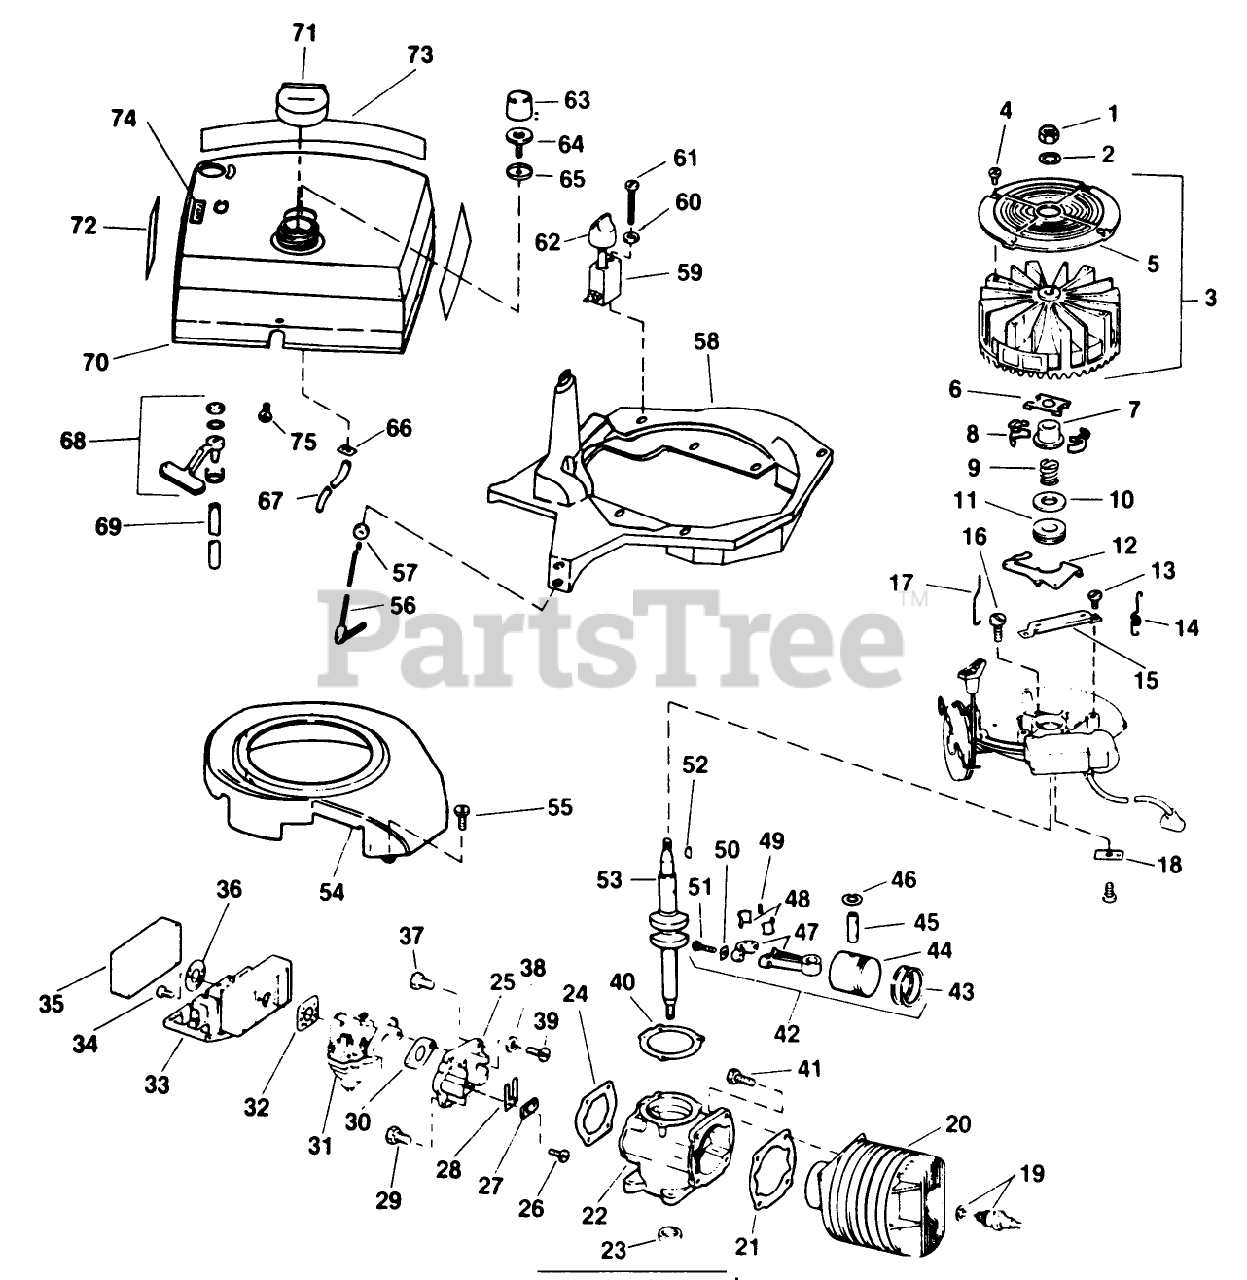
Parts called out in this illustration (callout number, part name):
1	NUT
4	SCREW F
6	YOKE S
7	COLLAR S
9	SPRING S
12	LEVER-GOVERNOR S
13	SCREW S
14	SPRING
15	BRACKET
16	SCREW S
17	ROD
18	TAB
19	Spark Plug Champion CJ-14 .035" Gap
21	GASKET S
24	GASKET S
27	PLATE-BACKUP, REED
29	SCREW S
30	GASKET S
32	GASKET S
33	CASE
34	SCREW S
35	AIR FILTER S
36	WASHER S
37	SCREW S
40	GASKET S
46	RING-RETAINING
48	LINER ASM
51	SCREW
52	KEY
54	BAFFLE
55	SCREW S
57	GROMMET
60	WASHER S
65	CUP-BULB
66	LOCKNUT S
75	SCREW S
